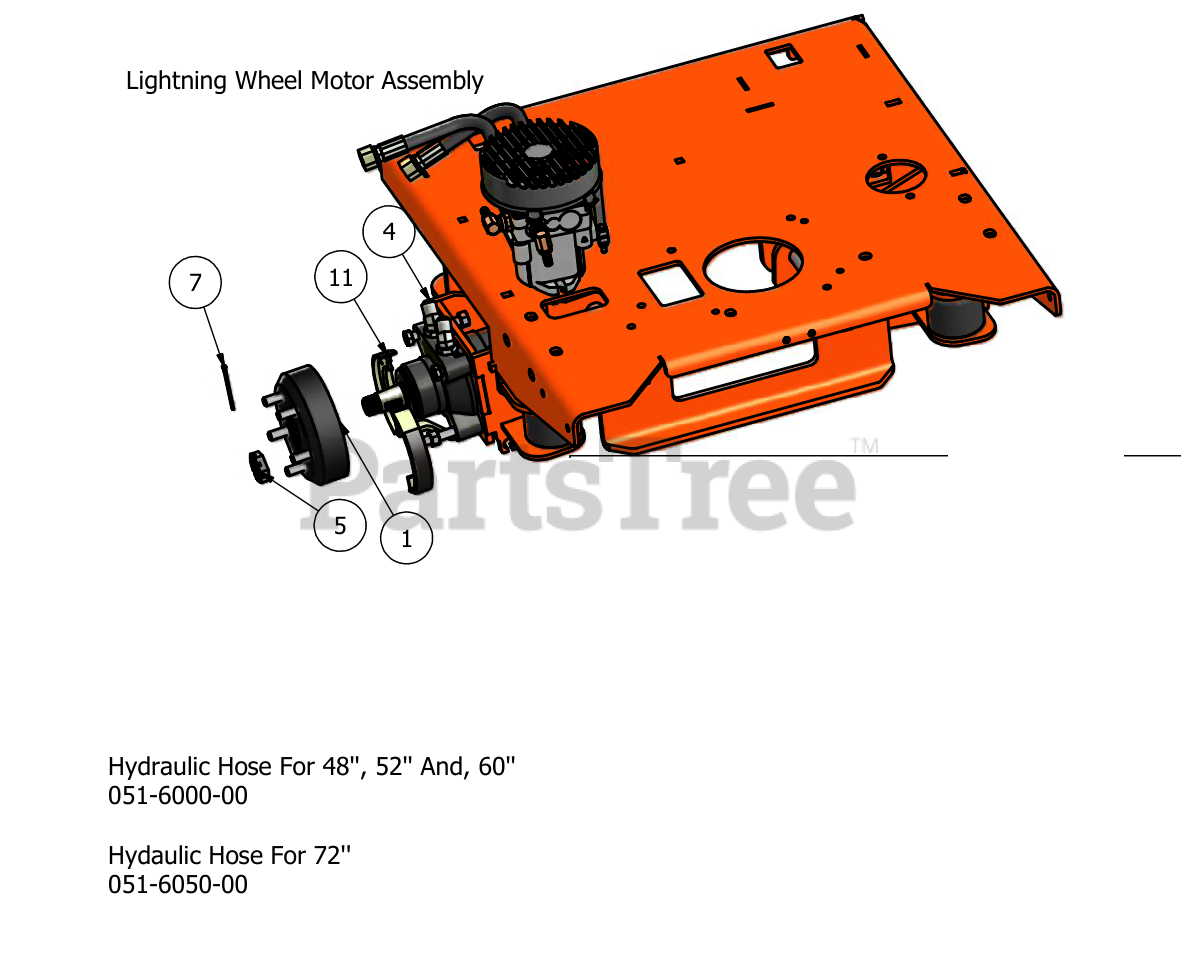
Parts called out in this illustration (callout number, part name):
1	Brake Drum
2	24" Tire and Wheel Assembly
3	12" Rim -60"&72" Cut
4	Hydraulic Fitting (Wheel Motor)
5	Castle Nut
7	1/8"x2 1/4" Cotter Pin
8	24x12-12 Tire 60"&72" Cut
10	23x10.50-12 Tire & Wheel
11	Brake Pads
12	23x10.50-12 Tire
13	12" Rim 48" & 52" Cut
